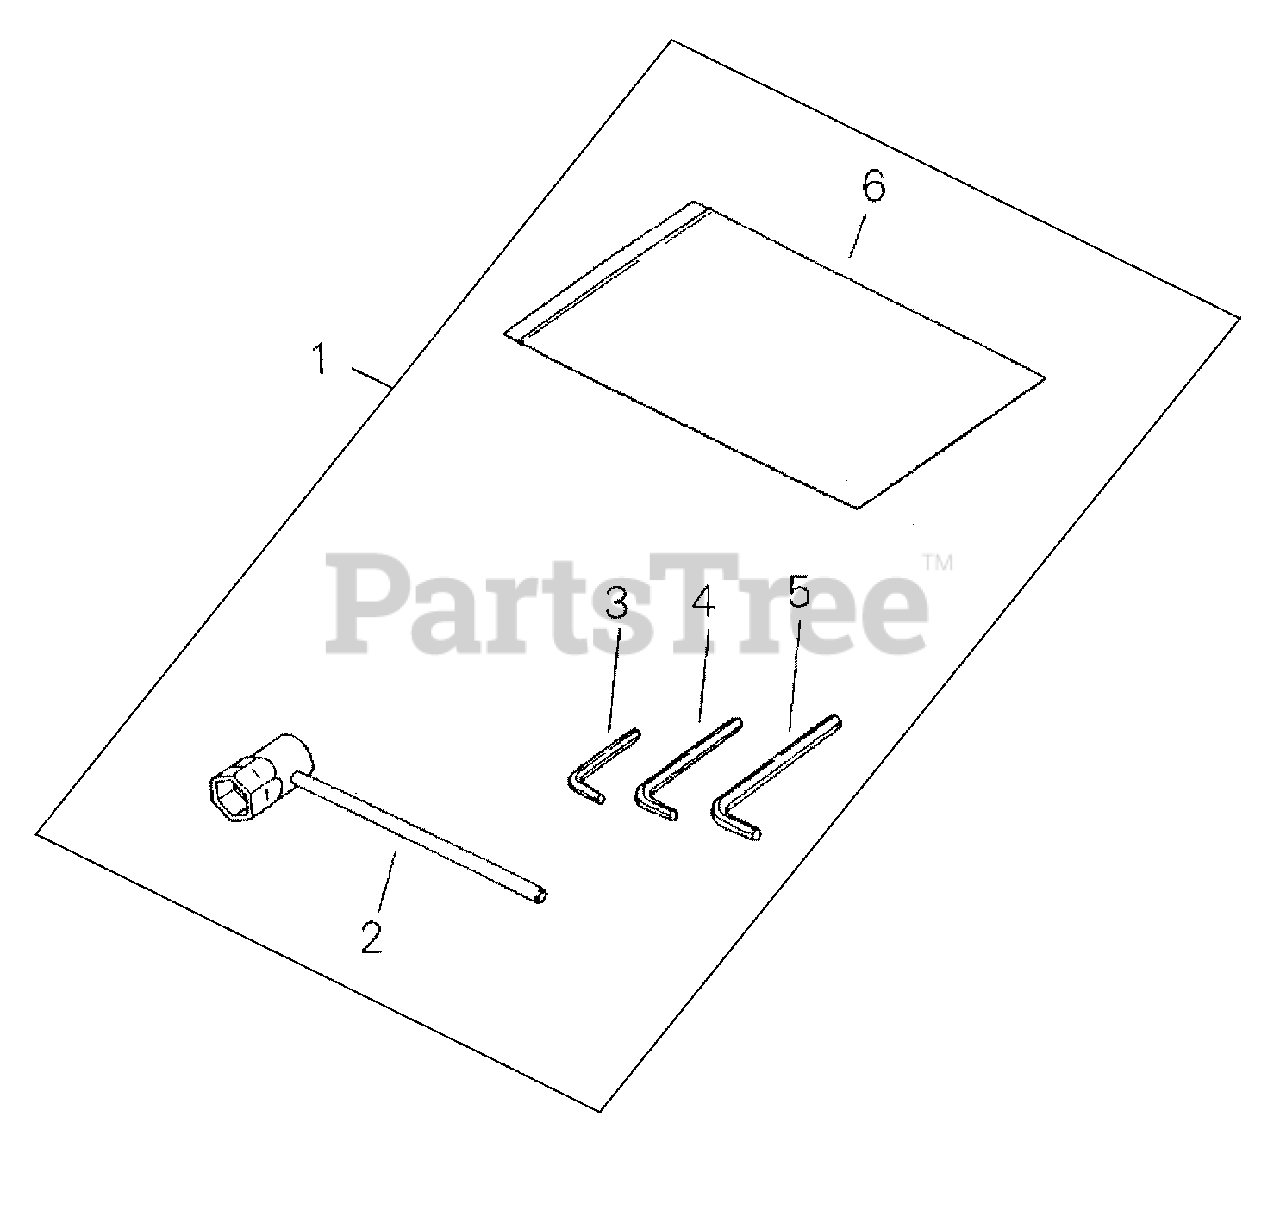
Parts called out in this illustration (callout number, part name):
1	TOOL KIT
2	SOCKET WRENCH
3	HEX KEY - 3mm
4	HEX KEY - 4mm
5	HEX KEY - 6mm
6	BAG, TOOL
